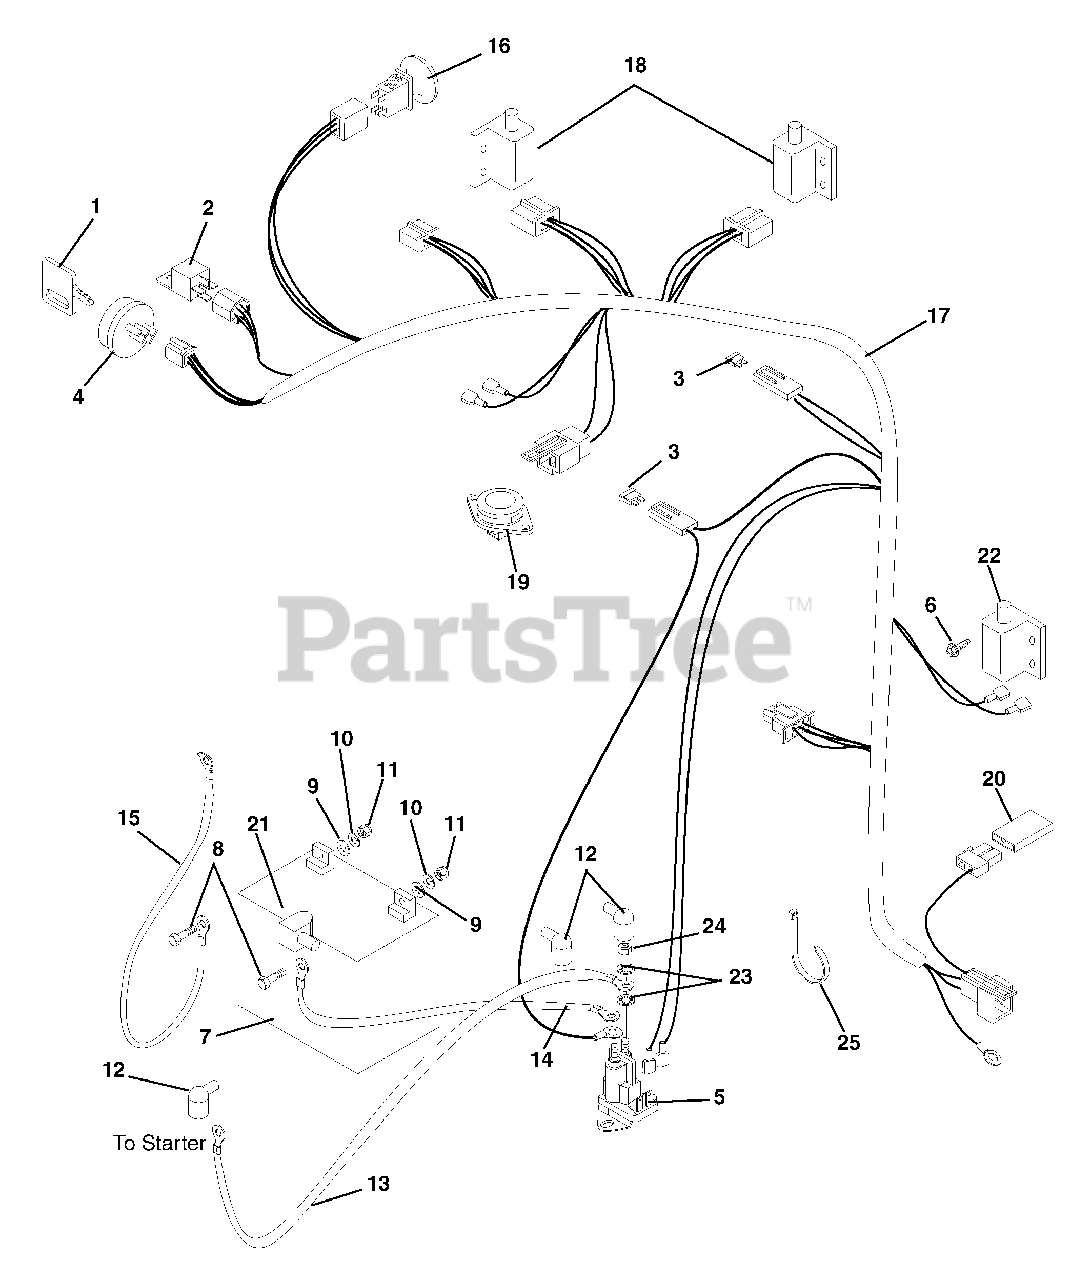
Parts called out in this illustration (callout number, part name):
1	Key with Cap
2	Relay
3	Fuse, 25 AMP
4	Key Switch
5	Solenoid
6	Screw, Tapping 10- 24 x .50 Hex Washer Head
7	Battery, Filled (043)
7	Battery with Tube (502)
8	Bolt, Hex .25-20 x .75 Grade 5
9	Washer, Flat Steel .281 x .62 x .065
10	Washer, Locking .25 x .062 Regular
11	Nut, Hex .25-20
12	Boot, Eyelet Terminal
13	Starter Cable 22"
14	Starter Cable 13"
15	Ground Cable
16	Switch, Clutch With Retainer
17	Wire Harness, Zoom 6 Pin
18	Switch, Double Pole N.O./N.O.
19	Switch, Snap Mounting (N.O.)
20	Diode, Connector Shell
21	Insulator
22	Switch, Interlock NC
23	Washer, Locking .31
24	Nut, Jam .31-24
25	Cable Tie
